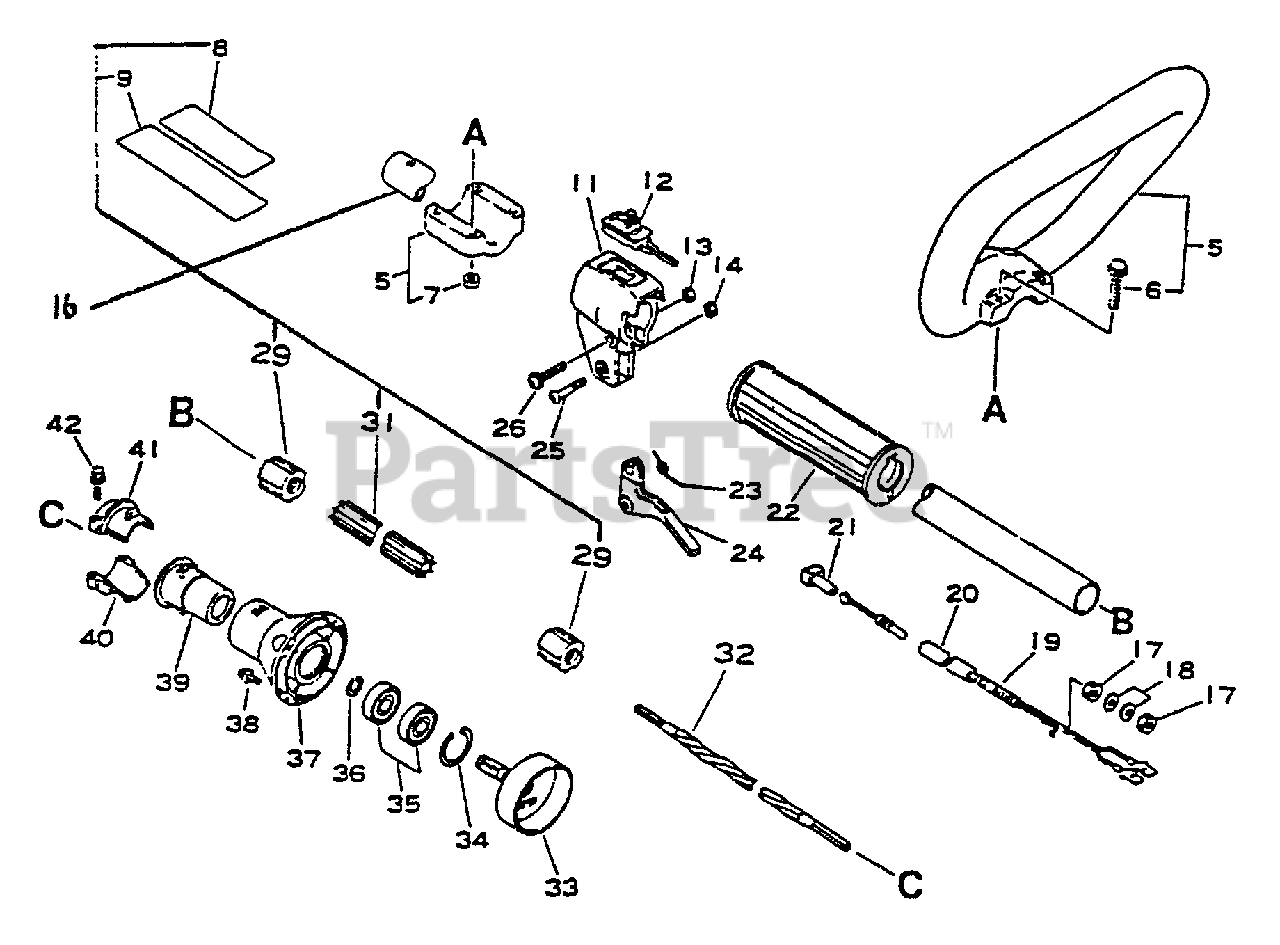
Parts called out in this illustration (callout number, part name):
5	LOOP HANDLE ASSY
7	SCREW - 6X35
8	LABEL - CAUTION
9	LABEL - CAUTION
11	BRACKET, THROTTLE CONTROL
12	IGNITION SWITCH ASSY
14	LOCKNUT - 5
16	MAIN PIPE ASSY
17	WASHER - 6
18	LOCKWASHER - 6
19	CABLE, THROTTLE
20	TUBE - VINYL
21	GUIDE, CABLE
22	GRIP, HANDLE
23	SPRING, TRIGGER
24	TRIGGER, THROTTLE
25	SCREW - 5X30
26	SCREW - 5X30
31	LINER - FLEXIBLE
32	DRIVESHAFT - FLEXIBLE
33	DRUM, CLUTCH
34	RING, RETAINING - 25
35	BEARING, BALL - 6001
36	RING, RETAINING - 12
37	CASE, CLUTCH
38	SCREW - 5X16
40	CLAMP, MAIN PIPE
41	CLAMP, MAIN PIPE - UPPER
42	BOLT - 5X25
